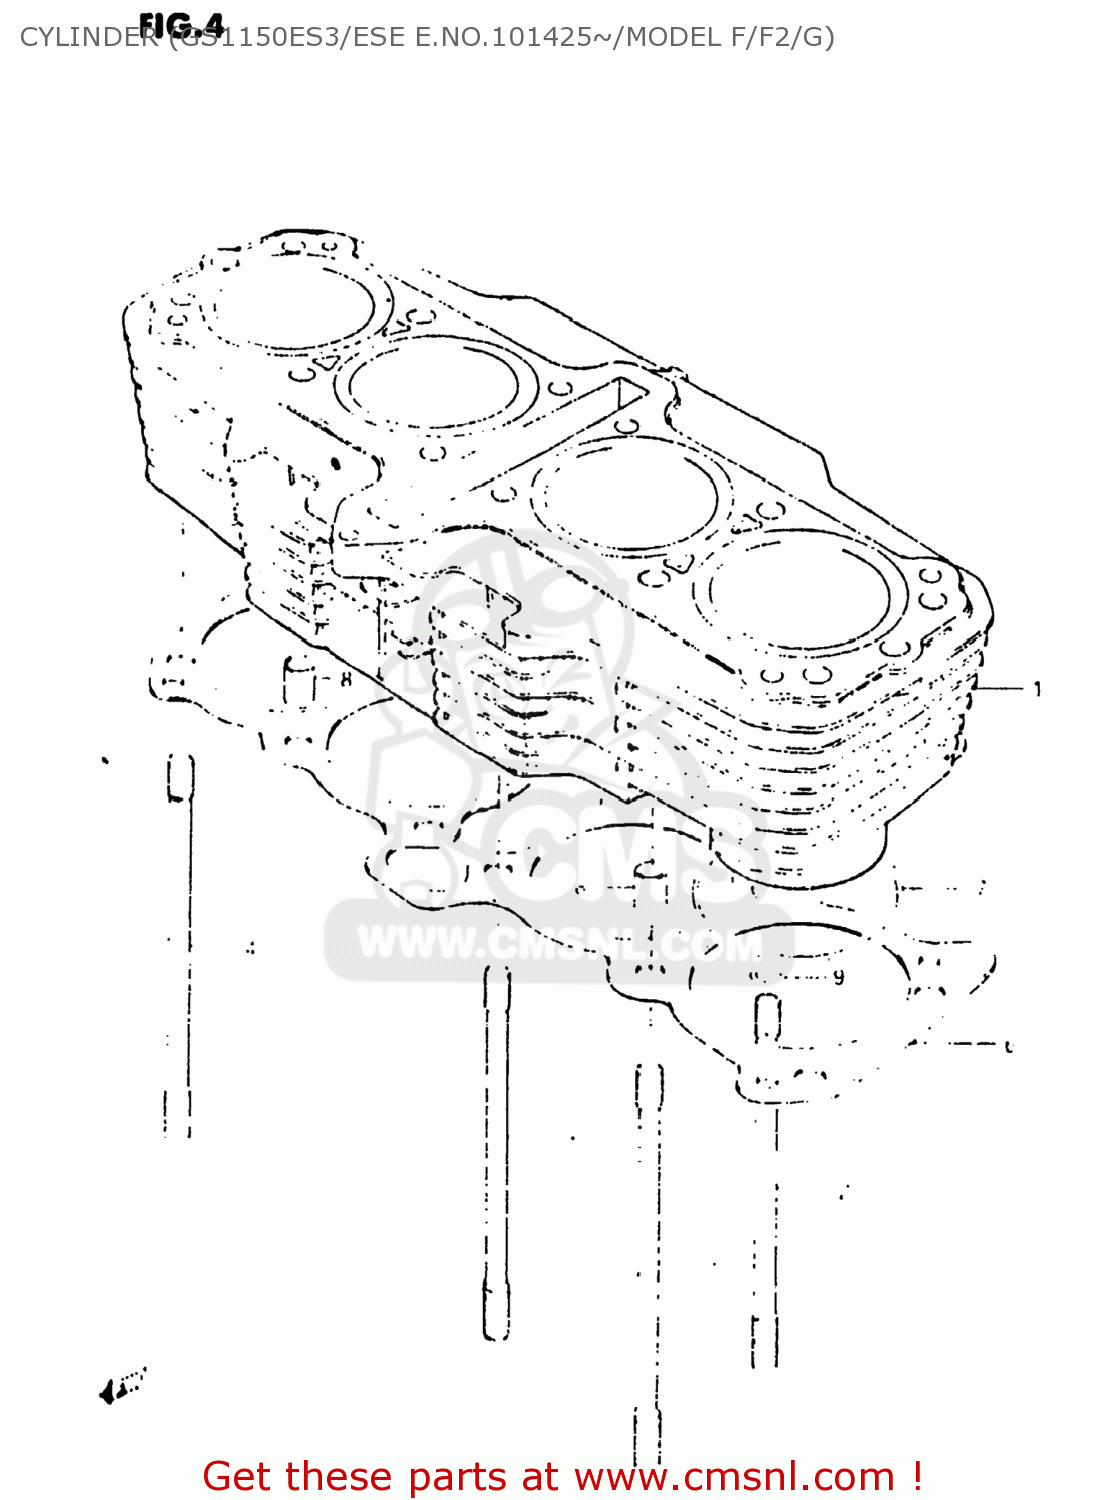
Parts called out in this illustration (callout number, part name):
1	CYLINDER
2	STUD
3	BOLT,STUD
4	STUD
5	BOLT,STUD
6	GASKET,CYLINDER HEAD (NAS)
7	O RING(D:2,ID:77)
8	PIN
9	O RING(D:2.4,ID:11)
